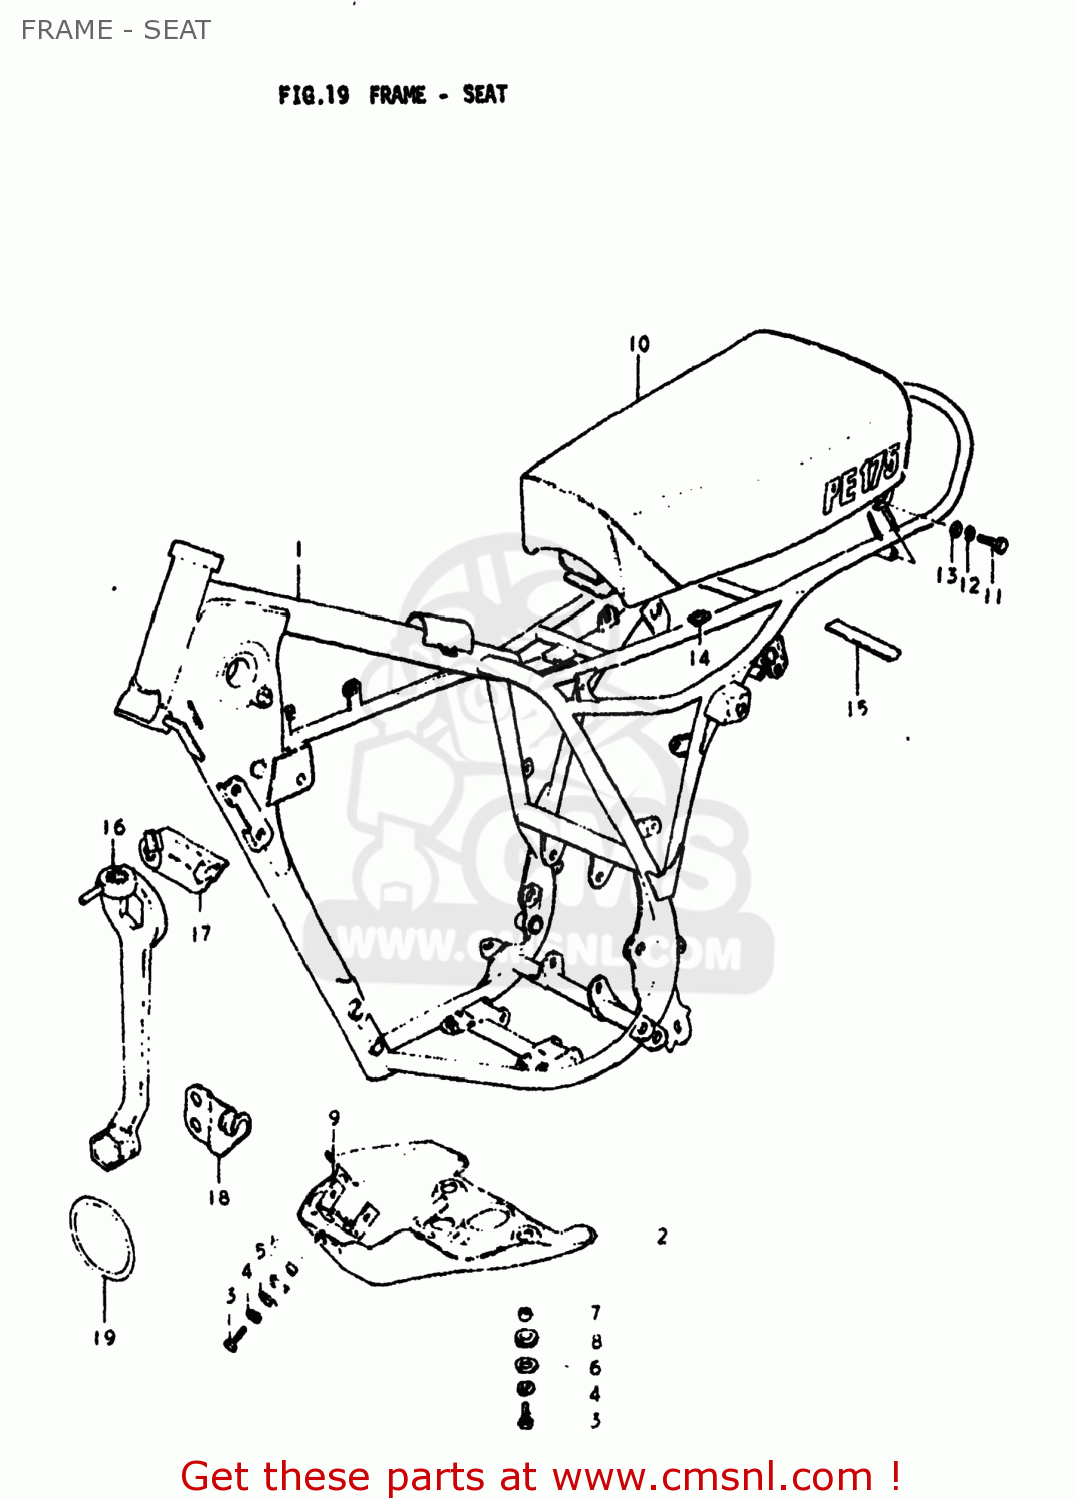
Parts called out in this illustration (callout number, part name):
1	FRAME
2	GROMMET
3	BOLT
4	LOCK WASHER
5	WASHER(8.5X26X1.2)
6	WASHER
7	SPACER (8.8X12X7)
8	CUSHION
9	BRACKET,ENGINE PROTECT
10	SEAT ASSEMBLY
11	BOLT
12	LOCK WASHER
13	WASHER
14	CUSHION
15	CUSHION,FRAME
16	SPARK PLUG/REAR
17	BRACKET,TOOL FITTING,UPPER
18	BRACKET,TOOL FITTING,LOWER
19	O RING,RR BRAKE CABLE
